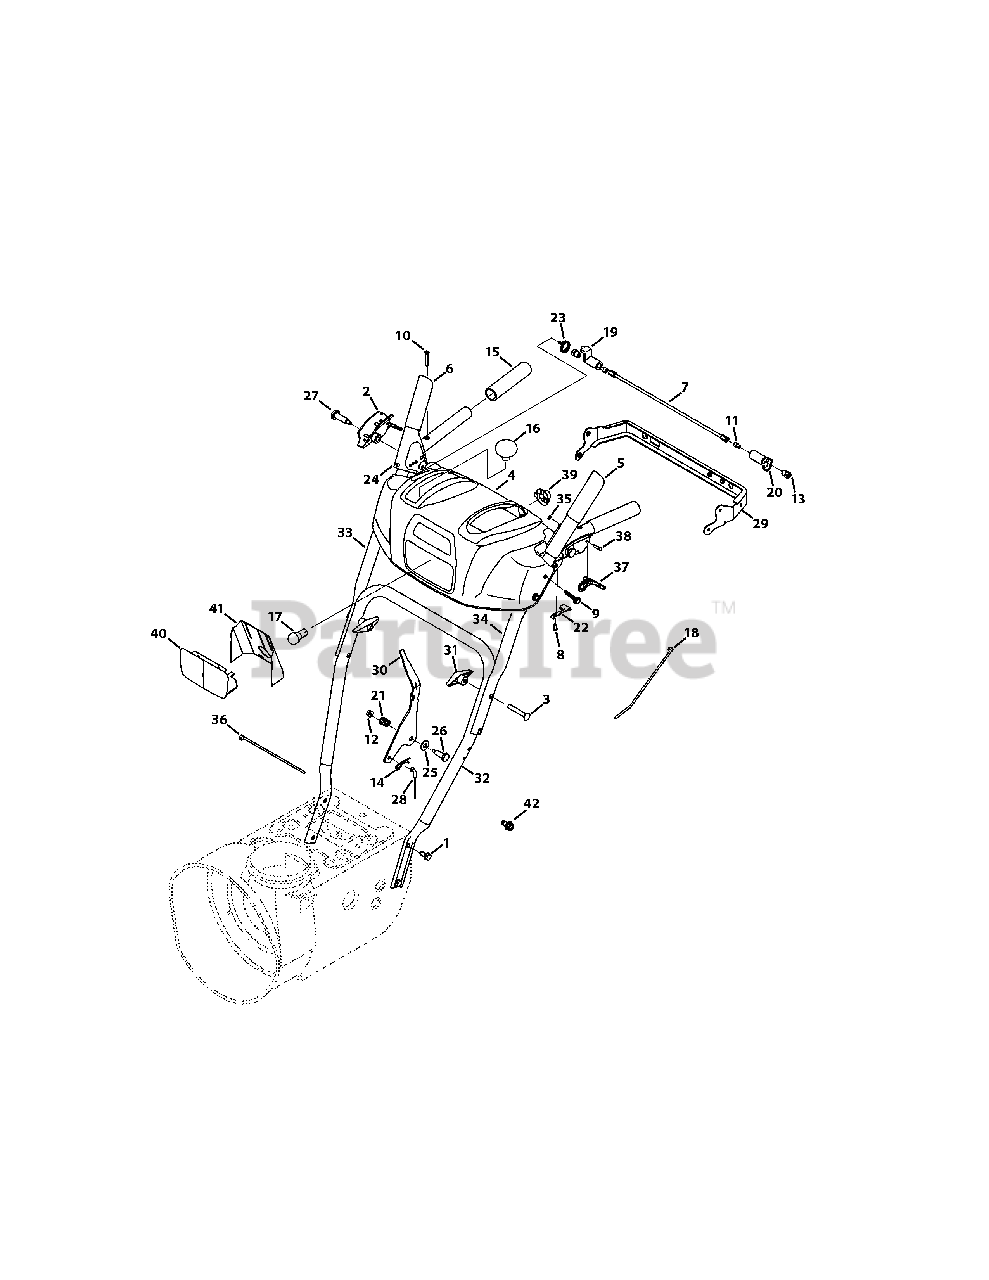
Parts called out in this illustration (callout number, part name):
1	Hex Screw, 5/16-18 x .750
2	Handle Clutch Lock LH Assy
2	Handle Clutch Lock RH Assy
3	Carriage Screw, 5/16-18 x 2.25
4	Handle Panel, includes Ref. 40 & 41
5	Handle Engagement Assembly LH
6	Handle Engagement Assembly RH
8	Screw, 8-16 x 0.50
9	Screw, 1/4-20 x 1.625
10	Screw, 10-24 x 1.375
11	Socket Screw, 1/4-20 x .50
12	Flange Lock Nut, 1/4-20
13	Shoulder Nut, 1/4-20
14	Click Pin, .092 x 1.64
15	Handle Grip
16	Shift Knob
17	Lamp
18	Cable Tie
20	Clutch Lock Cam
21	Compression Spring
22	Clutch Lock Spring
23	Torsion Spring
24	Rubber Bumper
25	Flat Washer, .385 x .87 x .06
26	Shoulder Screw, .374 x 1.05
27	Shoulder Screw, 1/4-20 x 1.345
28	Speed Cable Selector
29	Panel Bracket
30	Shift Lever
31	Wing Knob
32	Lower Handle
33	Upper Handle RH
34	Upper Handle LH
36	Cable Tie
37	Clutch Trigger
39	Light Socket
41	Lens Label
42	Screw, TT, 1/4-20 x .500
